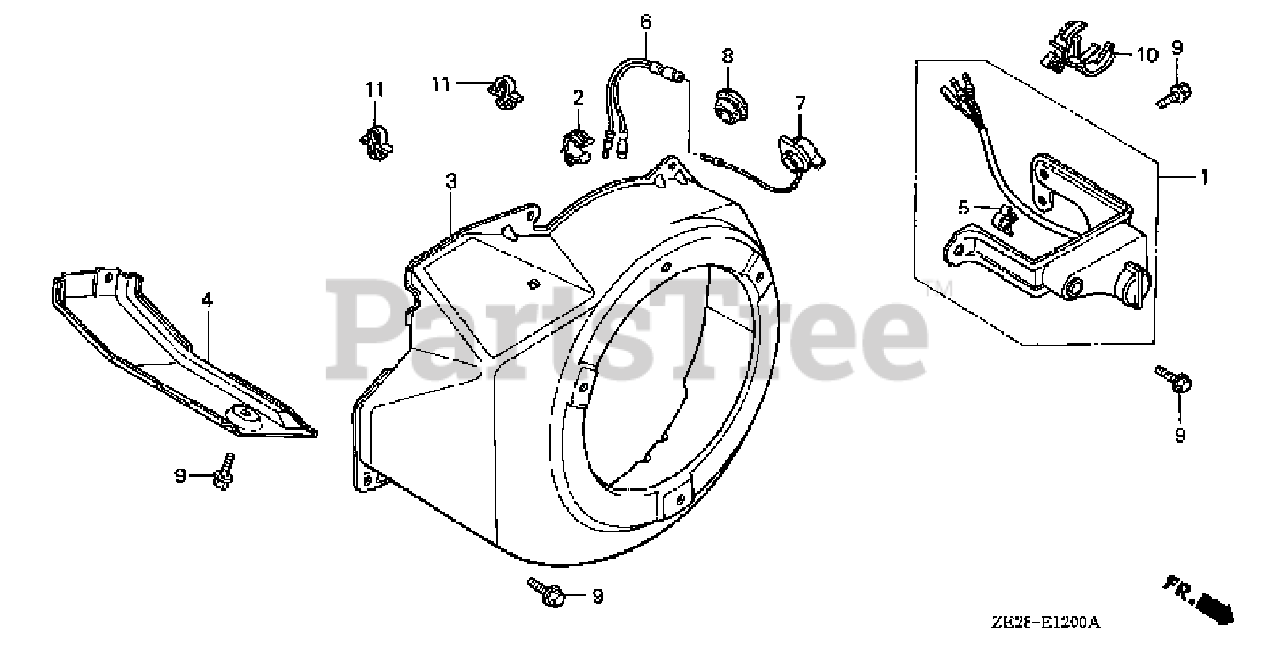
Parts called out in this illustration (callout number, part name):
1	ALERT UNIT, OIL
2	CLIP, TUBE
3	COVER, FAN *R8* (BRIGHT RED)
4	SHROUD
5	CLIP, IGNITION WIRE (8MM)
6	SUB-HARNESS
7	SWITCH ASSY., ENGINE STOP
8	GROMMET, DRAIN HOLE
9	BOLT, FLANGE (6X12) (CT200)
10	CLIP, WIRE HARNESS
